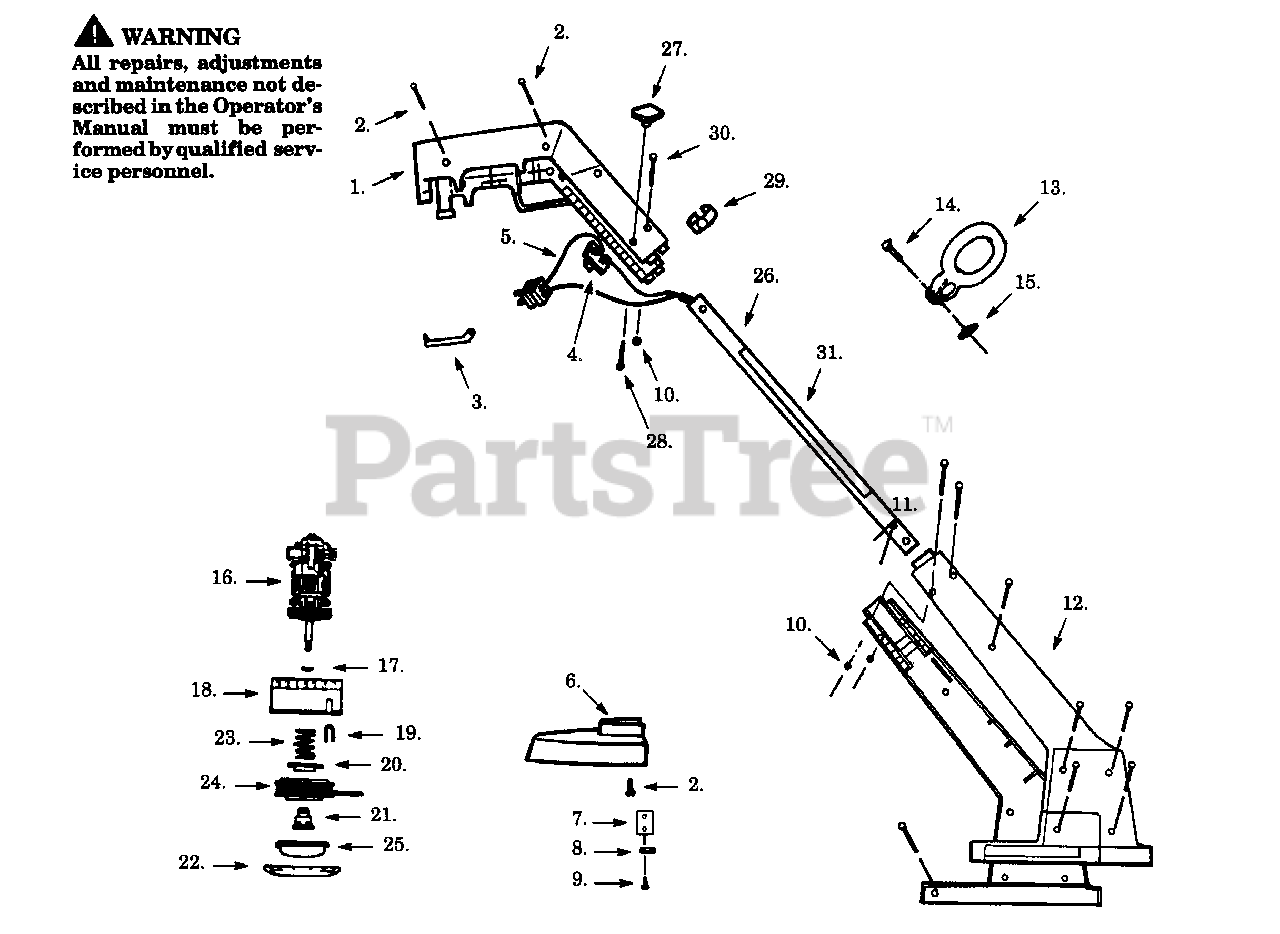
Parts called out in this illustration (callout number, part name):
1	Switch Handle Set, XT10, XT12
1	Switch Handle Set, TE30, TE31
4	On/Off Switch
5	Wiring Harness, XT10, XT12
5	Wiring Harness, TE30, TE31
6	Shield, XT10
6	Shield, XT12
6	Shield, TE30
6	Shield, TE31
7	Line Limiter
8	Blade Cover
12	Motor Hsg. Set, XT10, XT12
12	Motor Hsg. Set, TE30, TE31
13	Assist Handle, XT10, XT12
13	Assist Handle, TE30, TE31
15	Wing Nut
16	Motor Ass'y., XT10, TE30
16	Motor Ass'y., XT12, TE31
18	Hub, XT10, XT12
18	Hub, TE30, TE31
19	Line Saver
20	Spring Cap
21	Drive Gear Ass'y.
22	Cover, XT10, XT12
22	Cover, TE30, TE31
24	Spool w/Line
25	Tap Button, XT10, XT12
25	Tap Button, TE30, TE31
26	Tube Ass'y.
28	Screw TE30, TE31
29	Snap Button
31	Warning Decal
